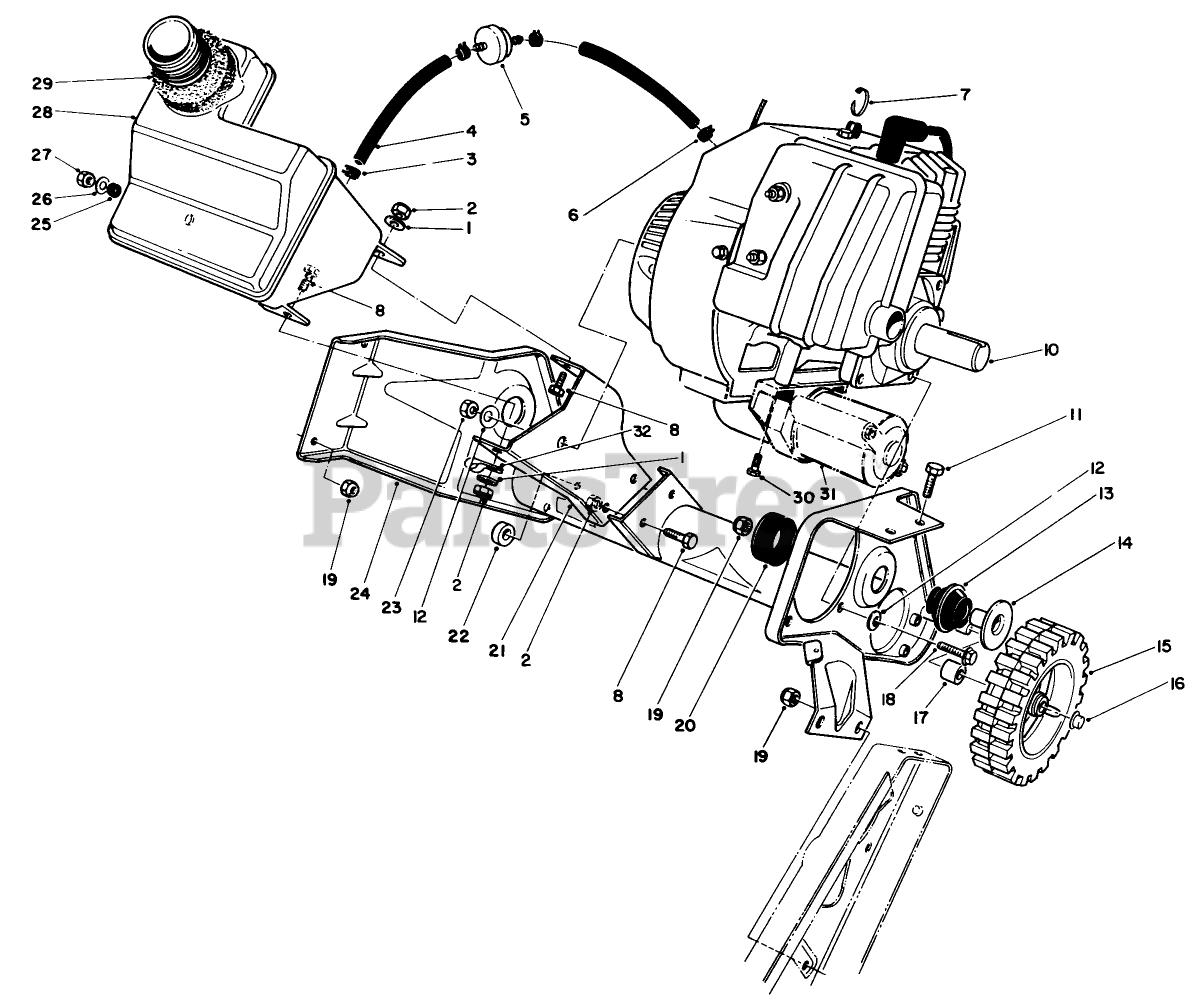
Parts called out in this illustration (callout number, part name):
1	WASHER-FLAT
2	NUT-LOCK, NI
3	Clamp
4	GAS LINE
5	FILTER-FUEL
6	CLAMP-HOSE
7	TIE-CABLE
8	SCREW-HH
10	Engine ASM
11	SCREW-HH
12	WASHER-BELLEVILLE
13	MOUNT-REBOUND
14	SPACER TUBE
15	WHEEL
16	NUT-PUSH
17	SPACER-WHEEL
19	NUT-LOCK, NI
20	LOAD MOUNT
21	Support-Recoil
22	SPACER-WHEEL
23	NUT (F/W & PPP)
24	Wa-Frame
25	GROMMET-RUBBER
26	WASHER-PLAIN
27	NUT-LOCK, CONE
28	Tank-Fuel(Incl. Ref. #25)
29	SEAL-FOAM
30	SCREW
31	Starter Motor Assembly
32	CLAMP
